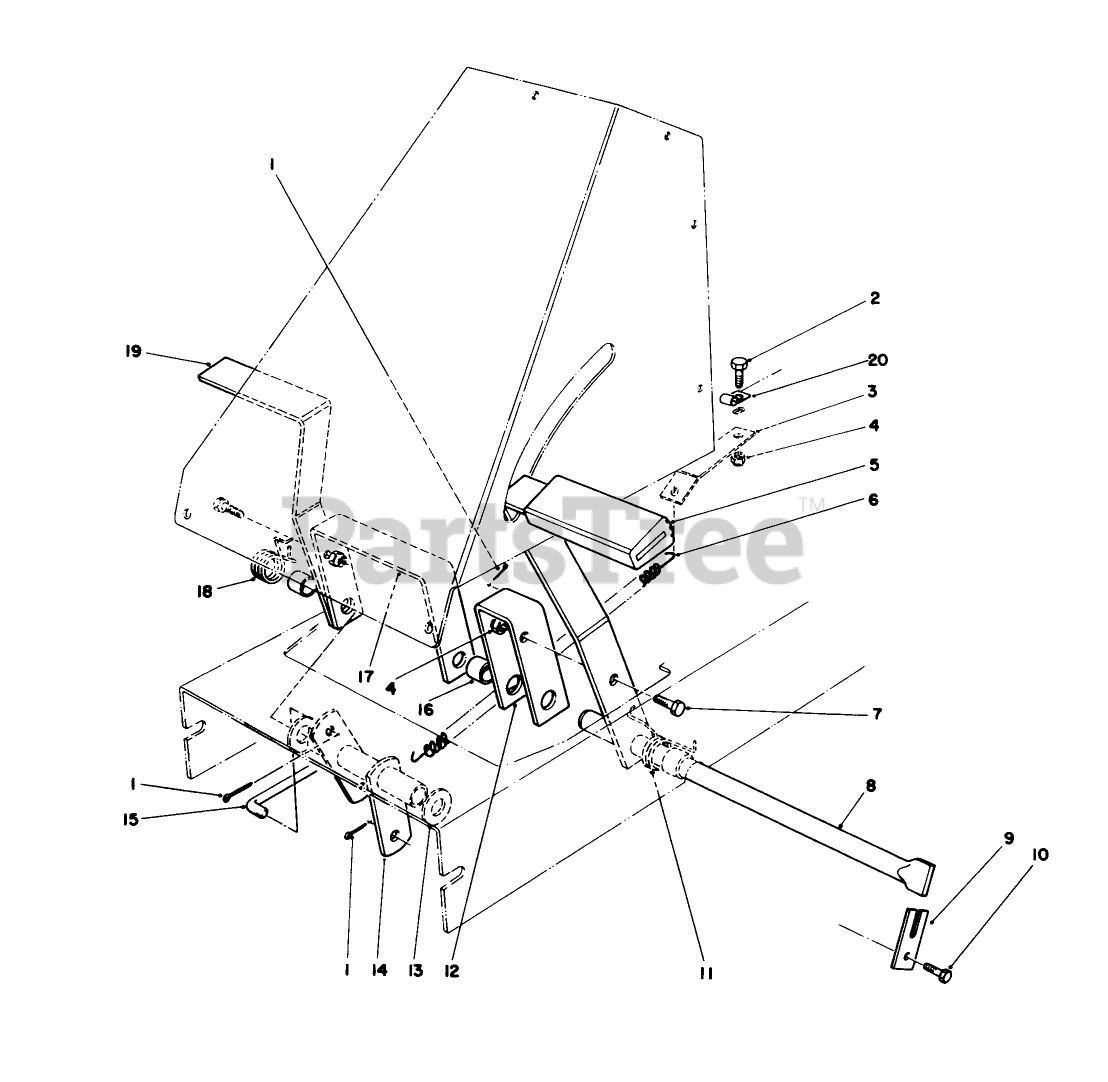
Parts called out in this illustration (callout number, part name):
1	PIN-COTTER
2	SCREW-HH
3	BRKT-SPRING RET
4	NUT-LOCK, NI
6	SPRING-EXTENSION
7	SCREW-HH
8	SHAFT-PEDAL PIVOT
9	RETAINER-SHAFT
10	SCREW-HH
11	SPRING-TORS CLUTCH
13	WASHER-FLAT
15	ROD-ENGAGE
16	SPACER-PEDAL
18	SPRING-TORS BRAKE
20	CLAMP
